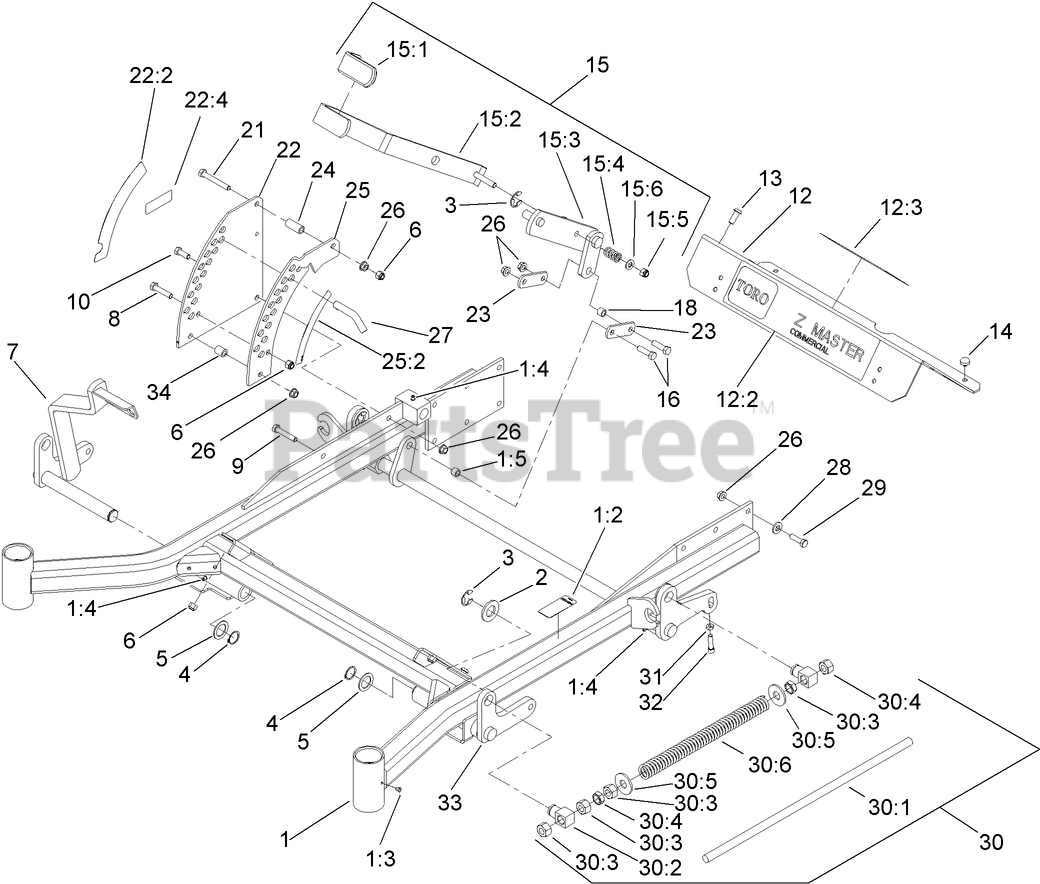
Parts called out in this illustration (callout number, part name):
1	FRAME ASM
1:2	Decal-Brake, Parking
1:4	FITTING-GREASE
1:5	Bushing
2	WASHER-FLAT
3	RING-RETAINING, EXT
4	RING-RETAINING
5	WASHER-SPACER
6	NUT-LOCK, NI
7	LIFT-DECK, RH FRONT
8	SCREW-HH
9	SCREW-HH
10	SCREW-HH
12	FOOTREST
12:3	DECAL-WARNING
13	SCREW-HSBH
14	BUMPER
15	DECK LIFT HANDLE ASM
15:1	GRIP-LEVER, LIFT
15:2	LEVER-LIFT
15:3	ARM-LIFT, DECK
15:4	SPRING-COMPRESSION
15:5	NUT-LOCK, NI
15:6	WASHER-FLAT
16	SCREW-HH
18	Bushing
21	SCREW-HH
22	PLATE-HOC, OUTER
22:2	Decal-Height, Deck
22:4	DECAL-ARRESTER, SPARK
23	ARM-LIFT, DECK
24	BUSHING-LEVER, LIFT
25	PLATE-HOC, INNER
25:2	Decal-Height, Deck
26	NUT-HHF, WHIZ
27	PIN-HOC
28	WASHER-BELLEVILLE
29	SCREW-HH
30	FRONT FRAME SPRING ASM
30:1	ROD-LIFT, DECK
30:2	SWIVEL-DECK MOUNT, REAR
30:3	NUT-HEX
30:4	NUT-JAM
30:5	WASHER-FLAT
30:6	SPRING-SUPPORT, DECK
31	NUT-JAM
32	SCREW-HSH
33	LIFT-DECK, LH
34	BUSHING-LEVER, LIFT
